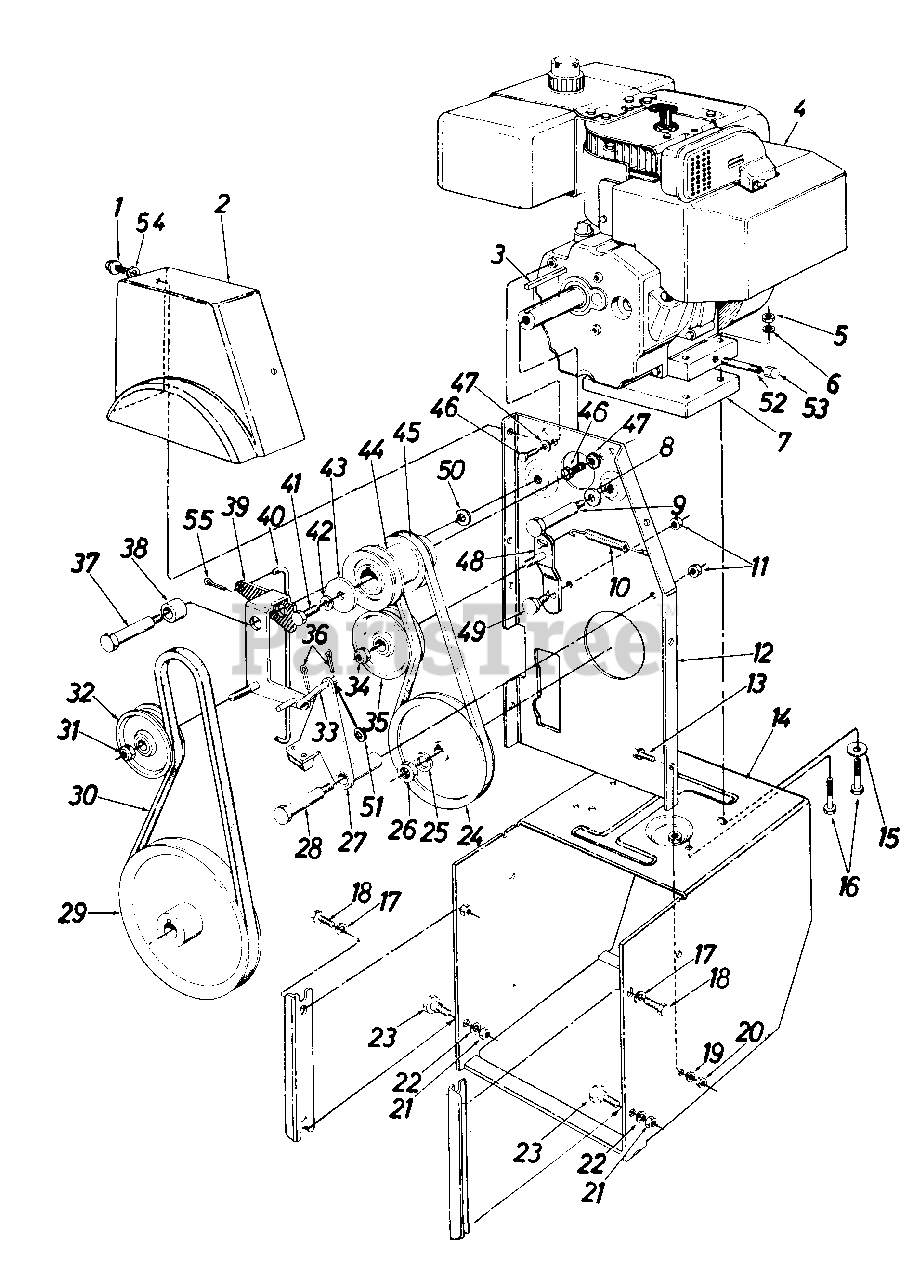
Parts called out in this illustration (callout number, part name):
1	Hex AB-Tap Scr. 5/16 x .75" Lg.
2	Belt Cover
3	Sq. Key 1/4" x 1.50" Lg.
4	Engine
5	Hex Nut 5/16-18 Thd.
6	L-Wash. 5/16" I.D.
7	Engine Spacer Ass'y.
8	Bell-Wash. .40 I.D. x .88 O.D.
9	Shld Bolt 498" Dia. x 3.00" Lg.
10	Ext. Spring .38 O.D. x 3.18" Lg.
11	Hex Cent. L-Nut 3/8-16 Thd.
12	Engine Brkt. Ass'y.
13	Hex Sems Scr. 5/16-18 x .75" Lg.
14	Frame Ass'y.
15	Fl-Wash. .345 I.D. x .75 O.D. x .060
16	Hex Bolt 5/16-18 x 2.50" Lg.
17	L-Wash. 3/8" I.D. H.D.
18	Pilot Scr. 3/8-16 x .88" Lg.
19	L-Wash. 5/16" I.D.
20	Hex Nut 5/16-18 Thd.
21	Hex Nut 3/8-16 Thd.
22	L-Wash. 3/8" I.D. H.D.
23	Shld. Bolt .498" Dia. x .340" Lg.
24	V-Pulley .628 I.D. x 7.50 O.D.
25	L-Wash. for 5/8" I.D.
26	Hex Ins. Jam L-Nut 5/8-18 Thd.
27	Brake Brkt. Ass'y.
28	Shld. Bolt .498" Dia. x 2.00" Lg.
29	V-Puiley .875 I.D. x 10.12 O.D.
30	"V"-Belt
31	Hex Ins. Jam L-Nut 3/8-24 Thd.
32	Fl-ldler w/Flanges 3.0 O.D.
33	Brake Linkage Ass'y.
34	Hex Ins. Jam L-Nut 3/8-24 Thd.
35	3.0" O.D. Fl-ldler w/Flanges
36	Int. Cot. Pin 3/32" Dia.
37	Shld. Bolt .625" Dia. x 2.750" Lg.
38	Spacer .75 O.D. x 1.00" Lg.
41	Hex Bolt 3/8-24 x 1.25" Lg.
42	L-Wash. 3/8" I.D. H.D.
43	Fl-Wash.
44	Engine Pulley-Double Groove
45	"V"-Belt
46	Hex Bolt 5/16-24 x .62" Lg.
47	Bell-Wash. .345 I.D. x .88 O.D. x .060
48	Drive Idler Brkt. Ass'y.
49	Shld. Bolt-.625" Dia. x .170" Lg.
50	Bell-Wash. .40 I.D. x 1.12 O.D.
51	Fl-Wash. .385" I.D. x .620" O.D.
52	Pipe Nipple-1/4" Pipe Thd. x 3.5" Lg.
53	Hex Hd. Cap 1/4-18 Pipe Thd.
54	Fl-Wash. .340 I.D. x .62 O.D. x .62
55	Int. Cot. Pin 5/16" Dia.
